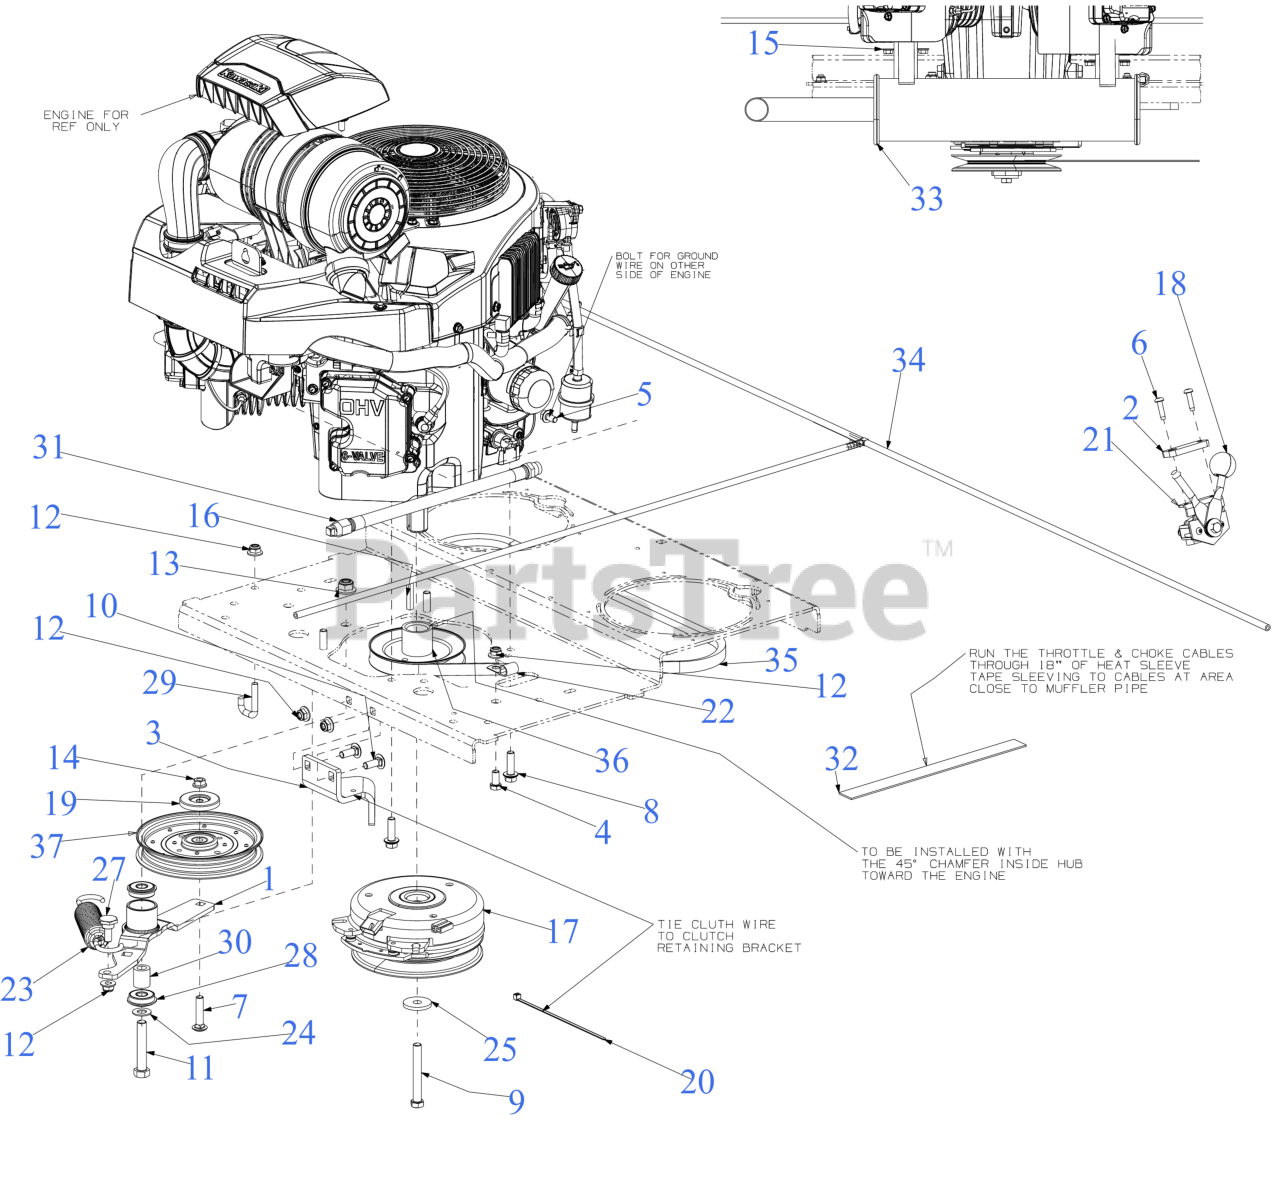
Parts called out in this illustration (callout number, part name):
1	TRANSMISSION IDLER BRACKET
3	CLUTCH RETAINER BRACKET
4	HEX SCREW 3/8-16 x .75
5	SCREW M8 x 1.25 x 16MM GR8.8
6	SCREW 1/4-20 x 1.0
7	CARRIAGE BOLT 3/8-16 x 1.75 GR5
8	SCREW 3/8-16 x 1.25 GR5
9	SCREW 7/16-20 x 3.25 GR5
10	CARRIAGE BOLT 3/8-16 x 1.00 GR5
11	SCREW 1/2-13 x 2.75 GR5
14	HEX LOCK NUT
15	HEX FLANGE NUT
16	SQUARE KEY 1/4 x 1.50
17	ELECTRIC PTO CLUTCH
19	PULLEY CAP
20	7" CABLE TIE
21	ELECTRONIC THROTTLE CONTROL
22	J TYPE CLIP
23	EXTENSION SPRING W/HOOK
24	FLAT WASHER .510 x .995
25	FLAT WASHER .45 x 1.5 x .172 HT
27	SHOULDER SCREW .625 x .302 x 3/8-16
28	ROLLER BEARING .5X1.37X.44
29	ROD SPRING HOOK
30	SPACER 0.51 x 0.88 x 1.00
31	OIL DRAIN HOSE
32	HEAT SHIELD 24"
33	MUFFLER - KAWASAKI 1000
35	TRANSMISSION BELT
36	DRIVE PULLEY
37	IDLER PULLEY
